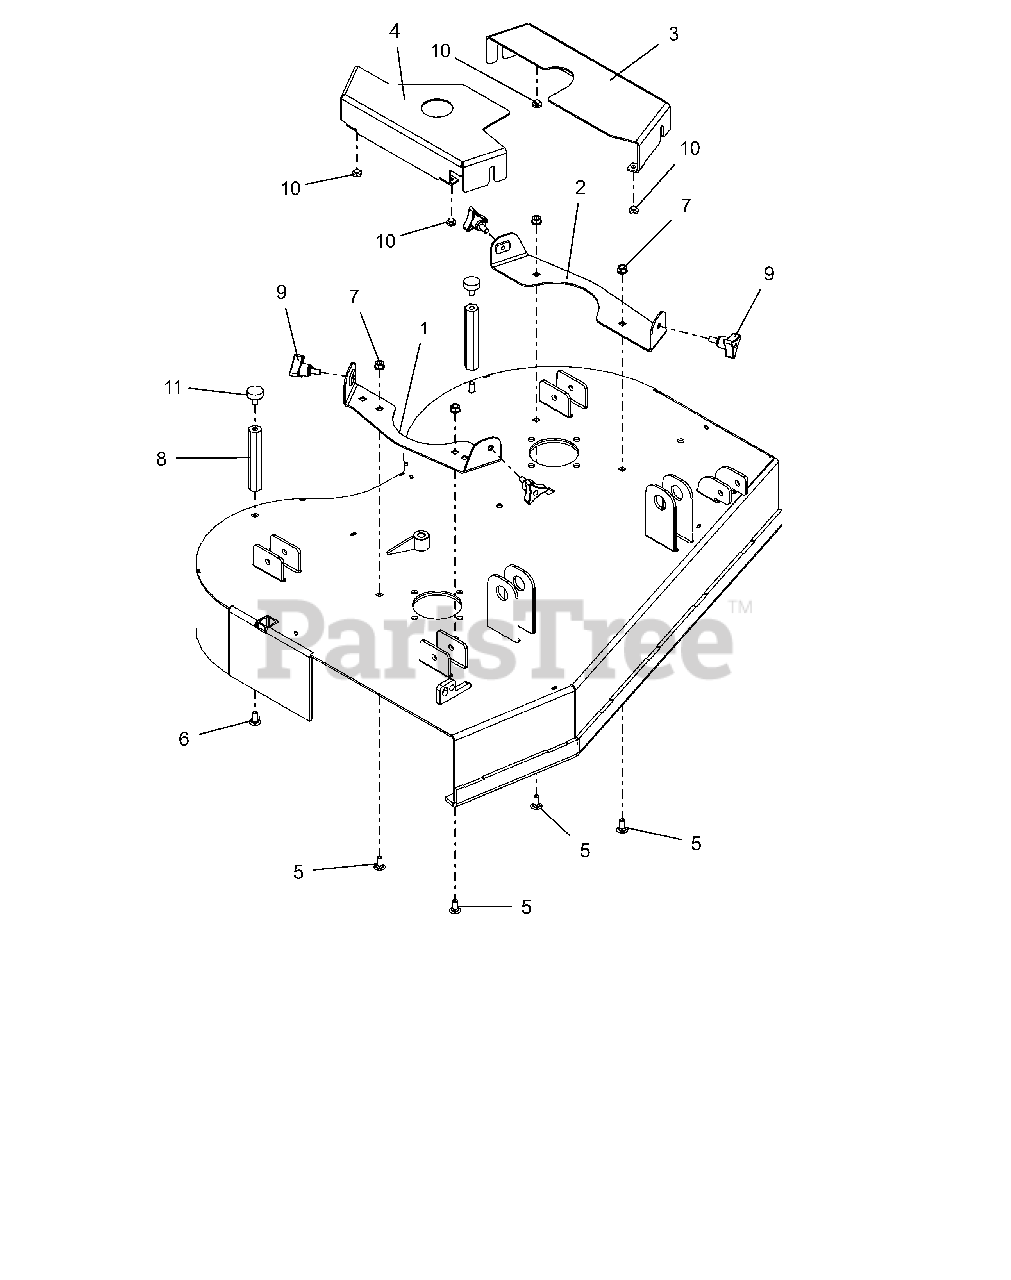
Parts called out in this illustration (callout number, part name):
1	WLDMT, BELT GUARD MTG BRKT
2	WLDMT, BELT GUARD MTG BRKT
3	GUARD, 34" LH DECK BELT
4	GUARD, RH DECK BELT
5	BLT,RHSN .31-18X.75 G5 ZCC
6	BLT, RHSSN.31-18X.750 G5 ZCC
7	NUT,LK-CTR-FLG .31-18 GF ZCC
8	NUT,.31-18 X 4.125 LG COUPLING
9	KNOB,WING STUD 5/16-18 X .75
10	BUMPER GROMMET
11	BUMPER, RUBBER
